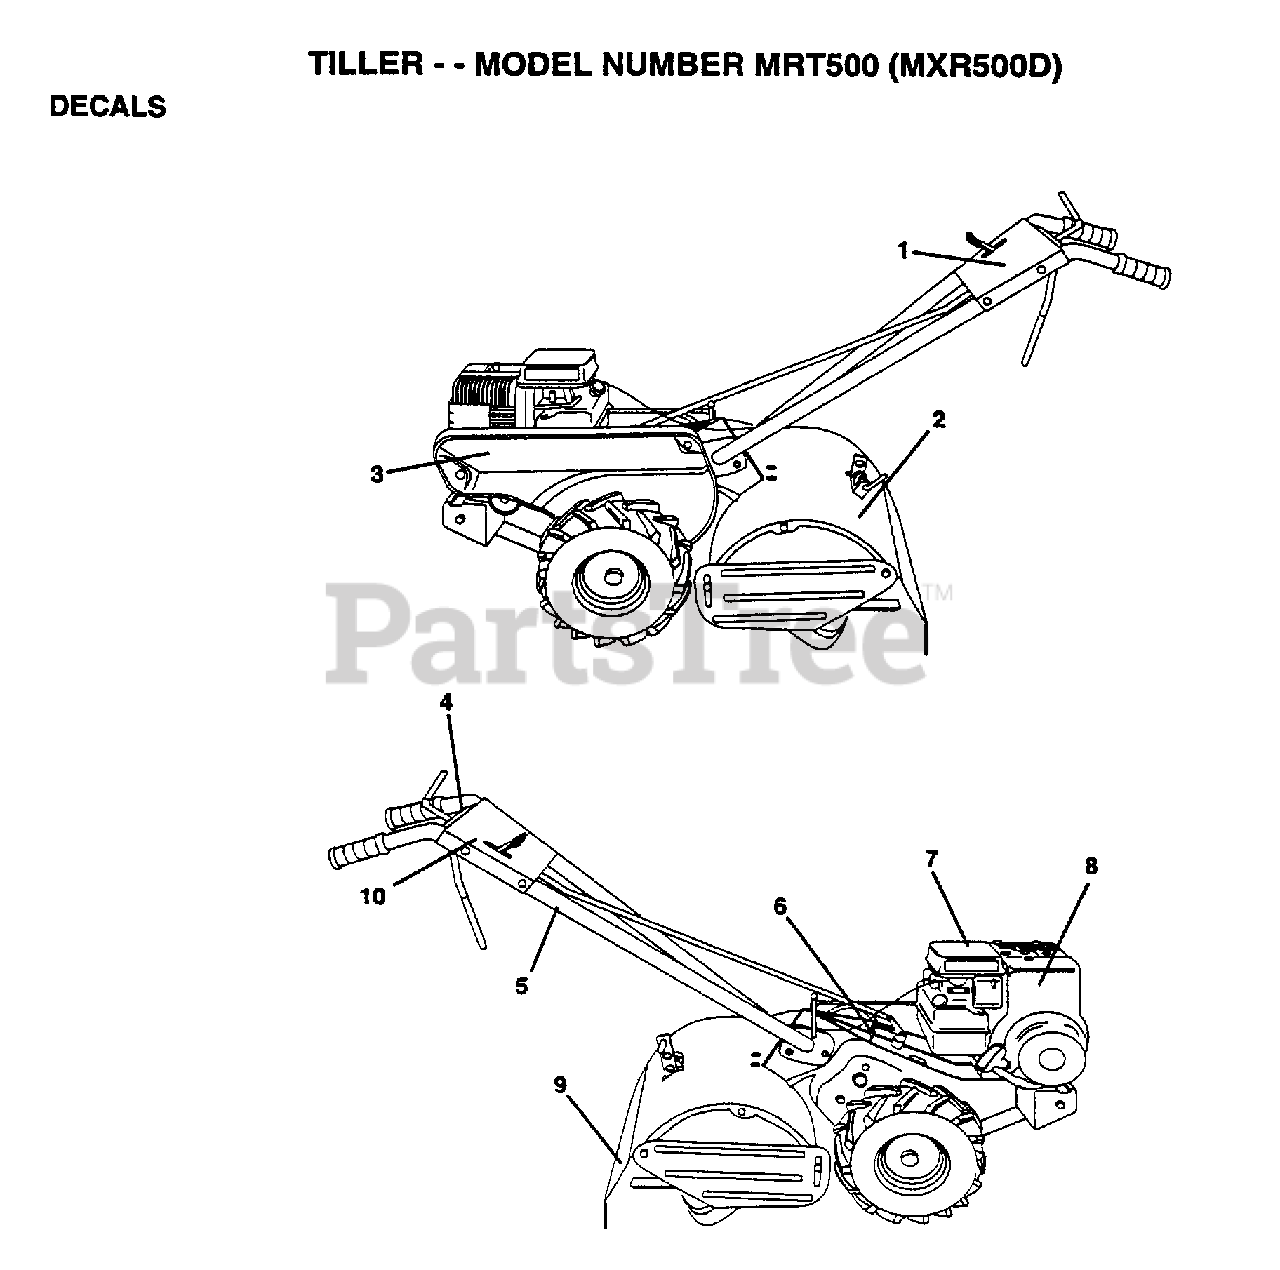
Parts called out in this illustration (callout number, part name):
1	DECAL CNTRL PANEL
2	DECAL SHIELD TINE
3	DECAL GUARD BELT
5	DECAL TI
7	DECAL TI
8	DECAL, BRIGGS & STRATTON
10	DECAL, THROTTLE
